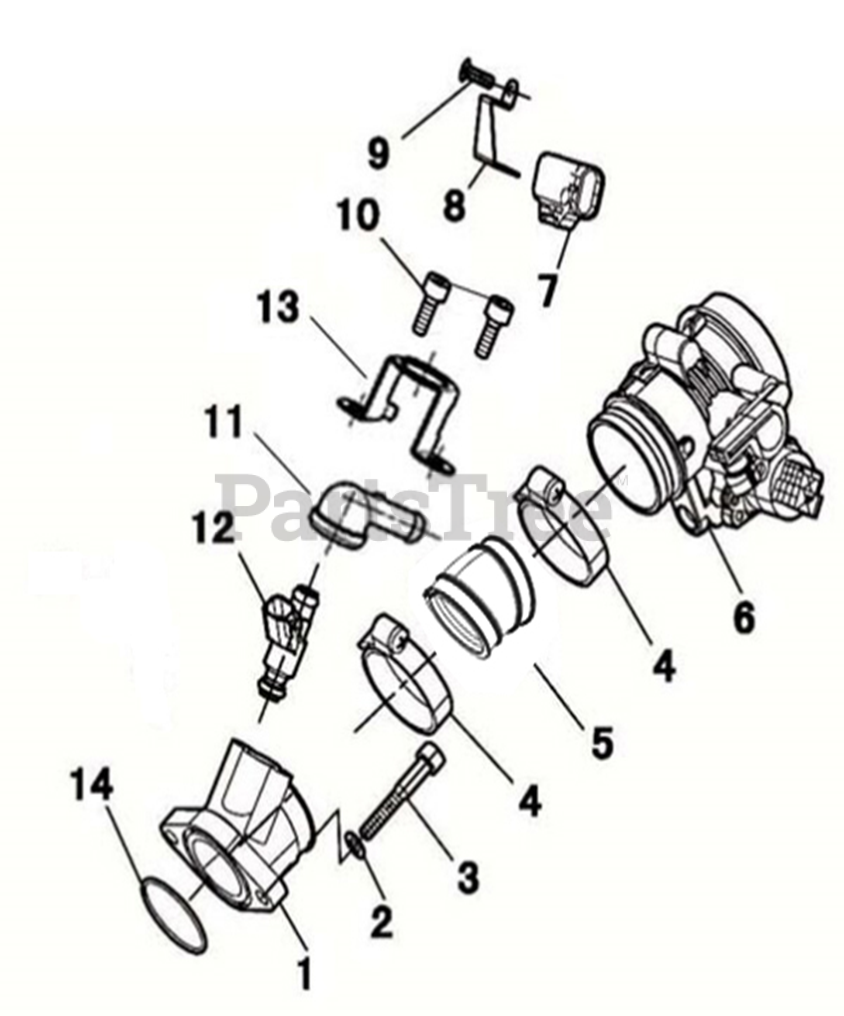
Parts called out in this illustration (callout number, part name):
1	ADAPTER ASSEMBLY
2	WASHER 8 x 16 x 1.5
3	HEX SOCKET HEAD CAP SCREW M8 x 50
4	HOSE CLAMP ASSEMBLY
5	INLET PIPE JOINT CURVED
6	AIR THROTTLE ASSEMBLY
7	TEMPERATURE/PRESSURE SENSOR
8	PRESS PLATE
9	CROSS RECESSED PANHEAD SCREW
10	HEX SOCKET HEAD CAP SCREW M6 x 12
11	FUEL INJECTOR FIXED SEAT
12	FUEL INJECTOR
13	FUEL INJECTOR CLAMP
14	O-RING 44 x 2
